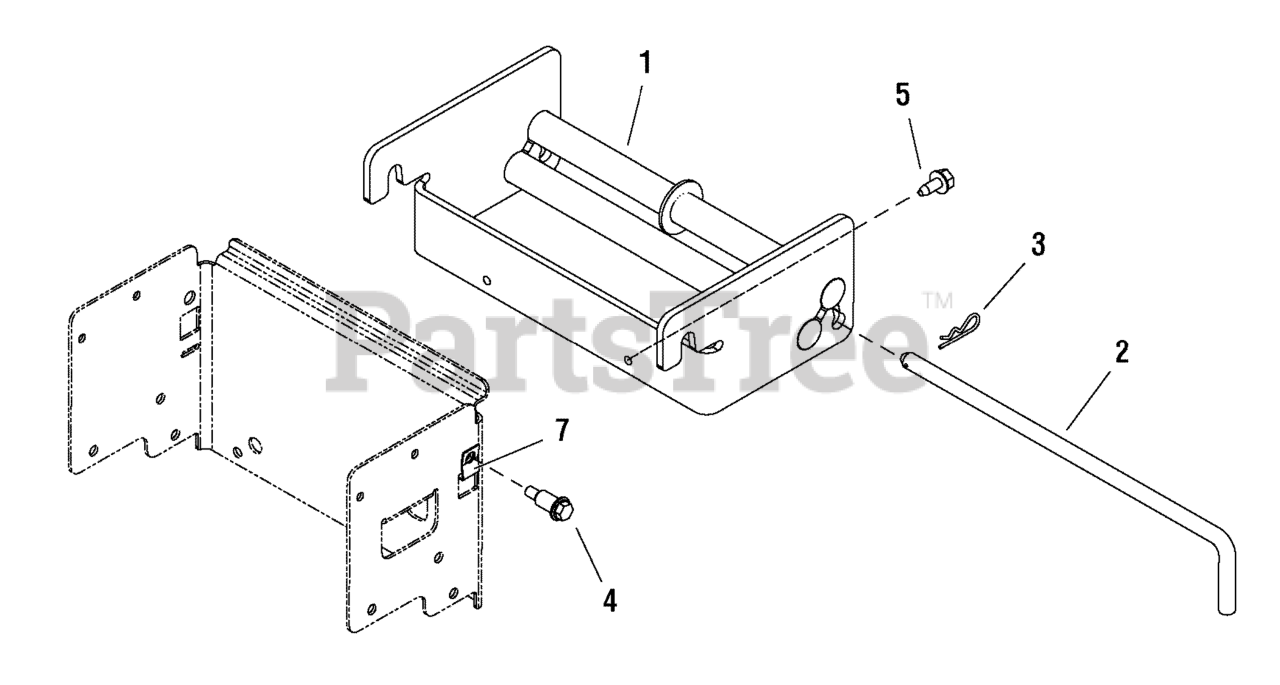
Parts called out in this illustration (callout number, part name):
1	SUPPORT ASSEMBLY, Weight Carrier
2	ROD, Latch
3	CLIP, Hair Pin
4	BOLT, Shoulder, 5/16-18 x 1-5/8
5	SCREW, Hex Washer Head Taptite, 5/16-18 x 3/4
7	NUT, Speed 5/16-18, Lug Type
